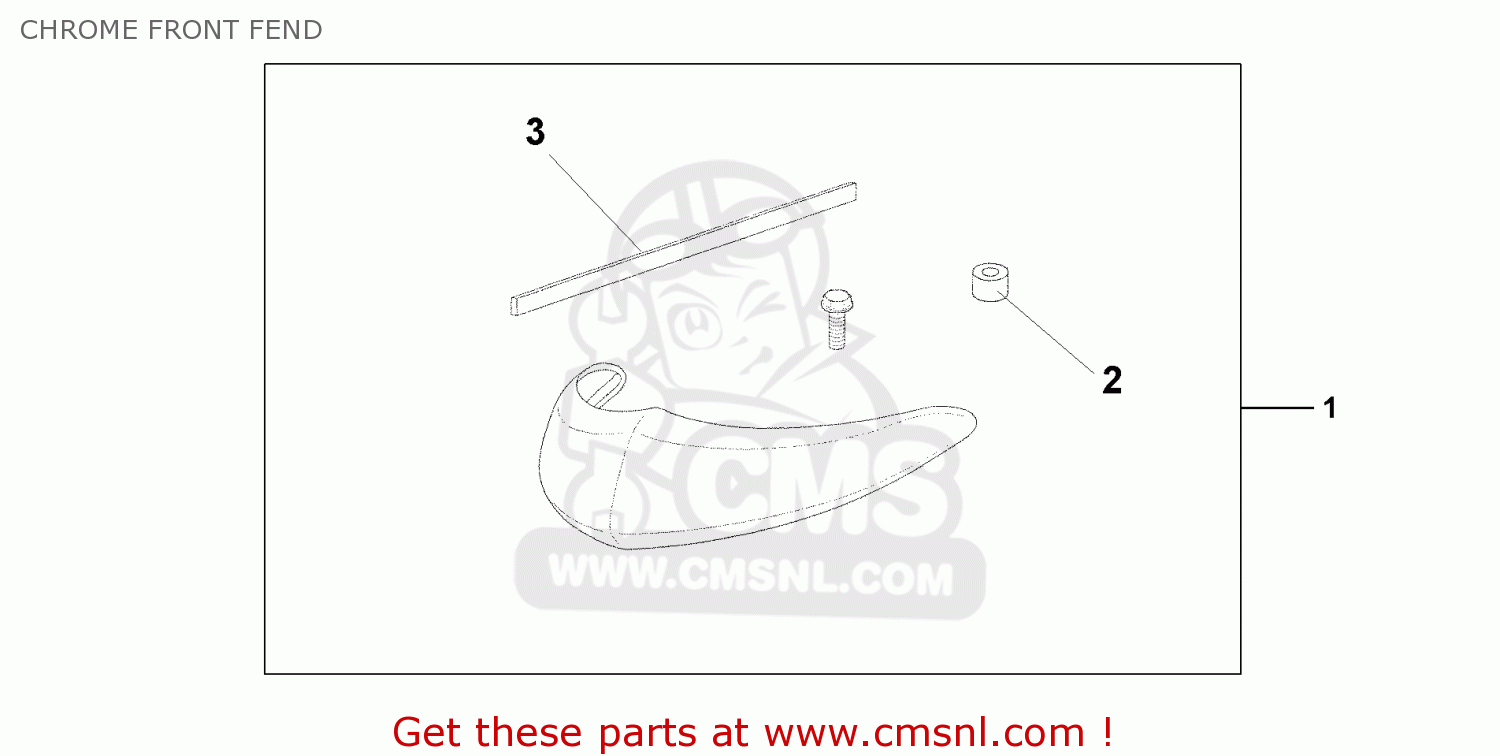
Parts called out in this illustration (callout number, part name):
1	CHROME FRONT FEND
2	BOLT,FLANGE,4X10
3	RUBBER,200X15X2
